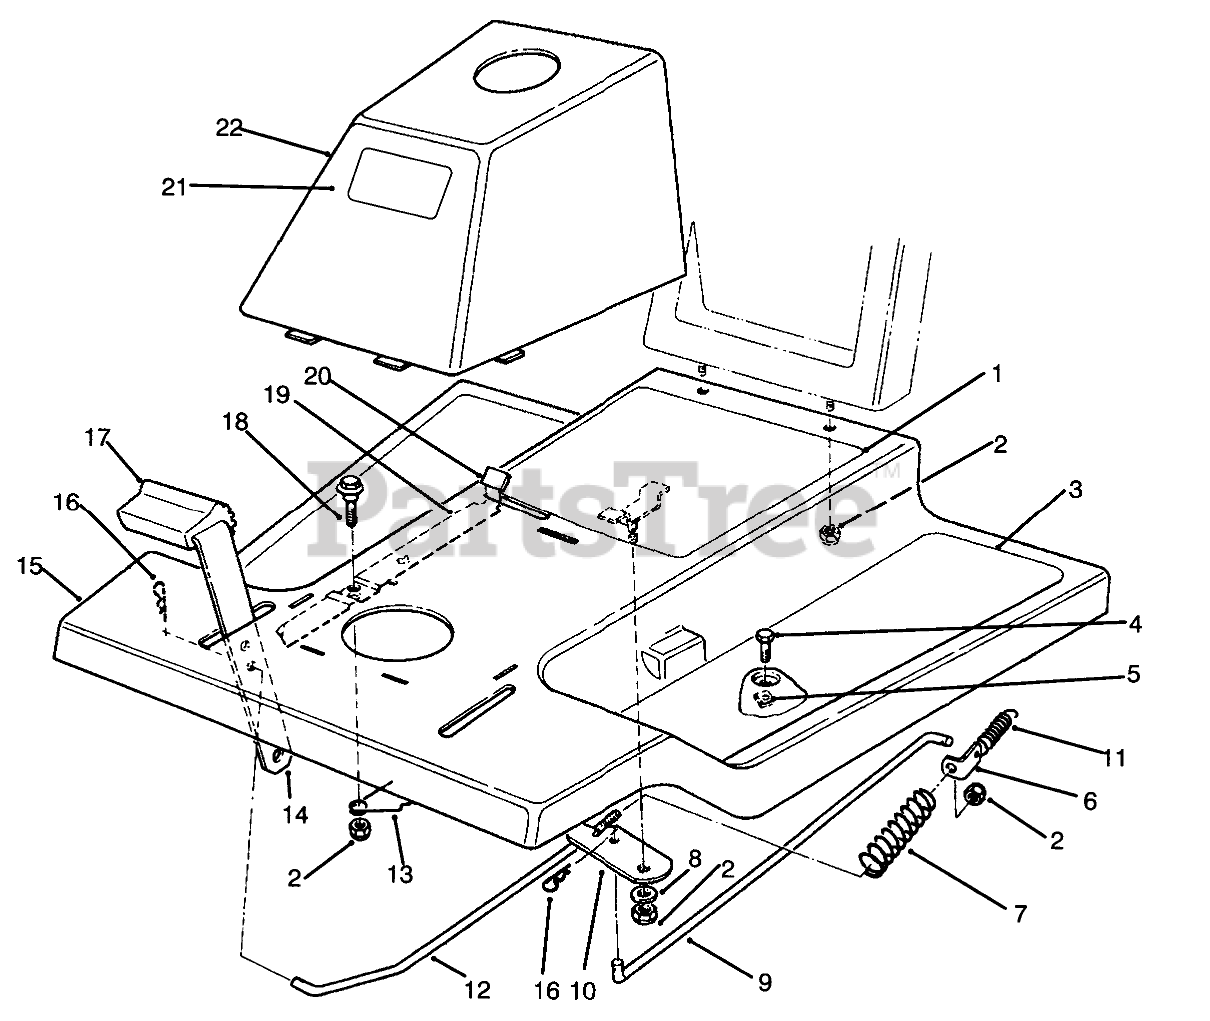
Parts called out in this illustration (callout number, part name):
1	DECAL - INSTRUCTION
2	NUT-LOCK, NI
3	TREAD-FOOT
4	SCREW-HH
5	NUT-TINNERMAN
6	BRACKET-BRAKE RETURN
7	SPRING-TRACTION BRAKE
8	WASHER-PIVOT
9	ROD-TRANS BRAKE
10	LEVER-BRAKE
11	SPRING-IDLER
12	ROD-FRONT BRAKE
13	SPRING-PARKING BRAKE
15	Body W.A.-Front
16	PIN-COTTER
17	PAD-PEDAL
18	SCREW-SHOULDER
19	PARKING BRAKE (BLACK)
20	TIP-PARKING BRAKE
21	DECAL
22	Tower (Incl. Ref. #21)
